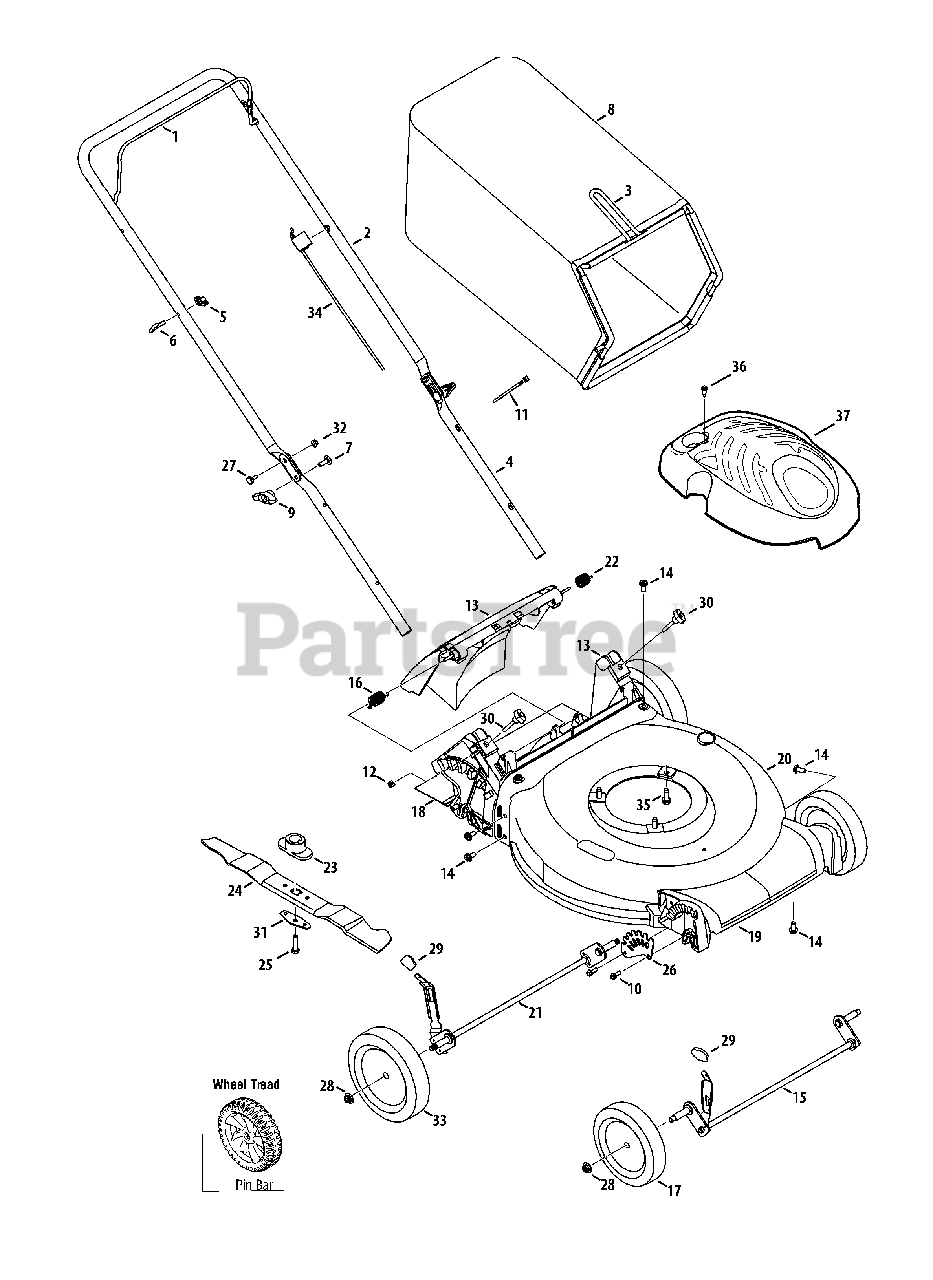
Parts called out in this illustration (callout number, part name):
1	Blade Control
2	Upper Handle
3	Grass Catcher Frame
4	Lower Handle
5	Wing Nut
6	Rope Guide
7	Carriage Screw, 5/16-18
8	Grass Bag
9	Wing Knob
10	Screw, 1/4-15 x .750
11	Cable Tie
12	Nut, Sq., 1/4-20
13	Rear Door Assembly
14	Screw, 5/16-14 x .750
15	Front Axle Assembly
16	Torsion Spring - RH
17	Front Wheel, 7 x 1.8, Bar, Gray
18	Trail Shield
19	Front Cover
20	Deck - 21"
21	Rear Axle Assembly
22	Torsion Spring - LH
23	Blade Adapter
24	Mulching Blade
25	Screw , 3/8-24 x 1.50
26	Front Height Adjuster Plate
27	Sldr. Screw, .375 x .126 x 1/4-20
28	Flange Lock Nut, 3/8-16
29	Adjustment Lever Knob
30	Wing Nut
31	Blade Bell Support
32	Nut, Flange Lock, 1/4-20
33	Rear Wheel, 8 x 1.8, Bar, Gray
34	Control Cable, 48"
35	TT Sems Screw, 3/8-16 x 1.0
36	Wave Washer, .510 x .750 x .017
37	Screw, HL, #12-16 x 1.00
38	Engine Shroud M1.1 Black
